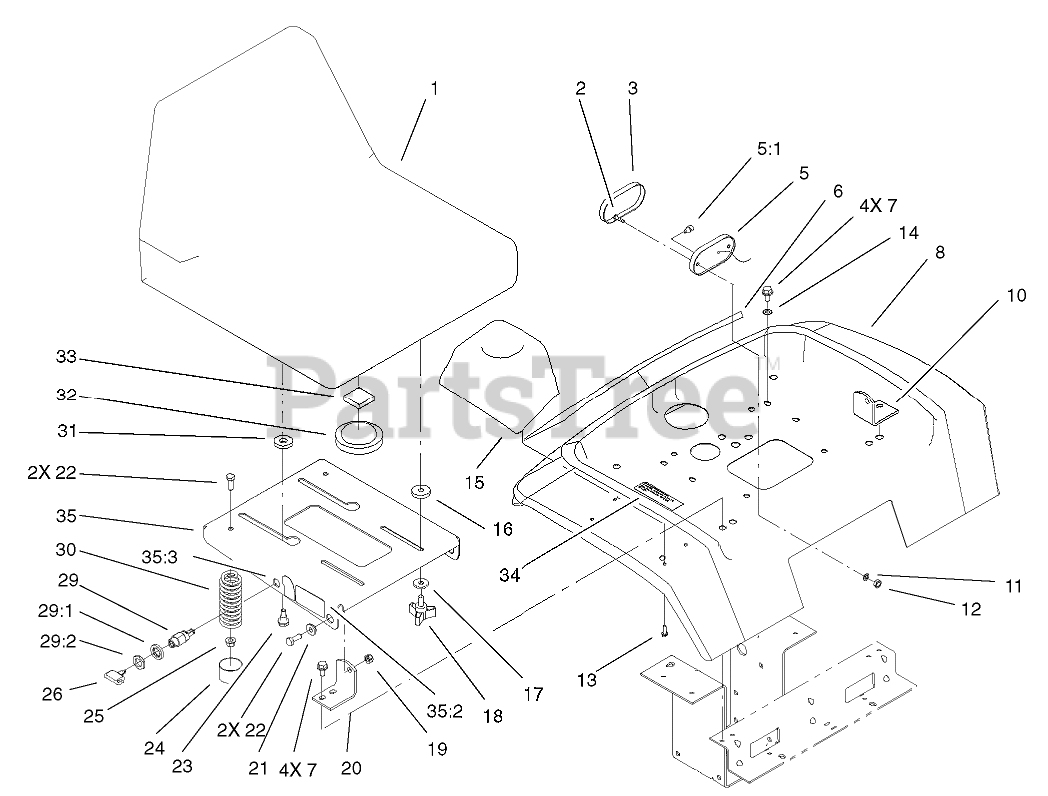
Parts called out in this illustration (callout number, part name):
1	SEAT
2	SCREW-PPH
3	LENS-TAIL LIGHT
5	BASE-TAIL LIGHT
6	DECAL - REAR FENDER
7	SCREW-HWHTF
10	BRACKET-PIVOT, LH
11	WASHER-LOCK, INT
12	NUT-LOCK, NI
13	SCREW-HHFTF
14	WASHER-LOCK
15	HOLDER-CUP
16	SPACER-NYLON
17	WASHER
19	NUT-LOCK, NI
20	BRACKET-PIVOT, RH
21	BUSHING
22	SCREW-HH
23	BOLT-SHOULDER
24	CAP-PROTECTOR
25	NUT-LOCK, NI
26	KEY-IGNITION
29	STARTER SWITCH ASM
29:1	WASHER-TOOTH, INTERNAL
29:2	NUT-HH
30	SPRING-COMPRESSION
31	SPACER-NYLON
32	SWITCH-SEAT
33	FOAM-SWITCH, SEAT
35	SUPPORT SEAT ASM
35:2	DECAL-DANGER
35:3	DECAL
